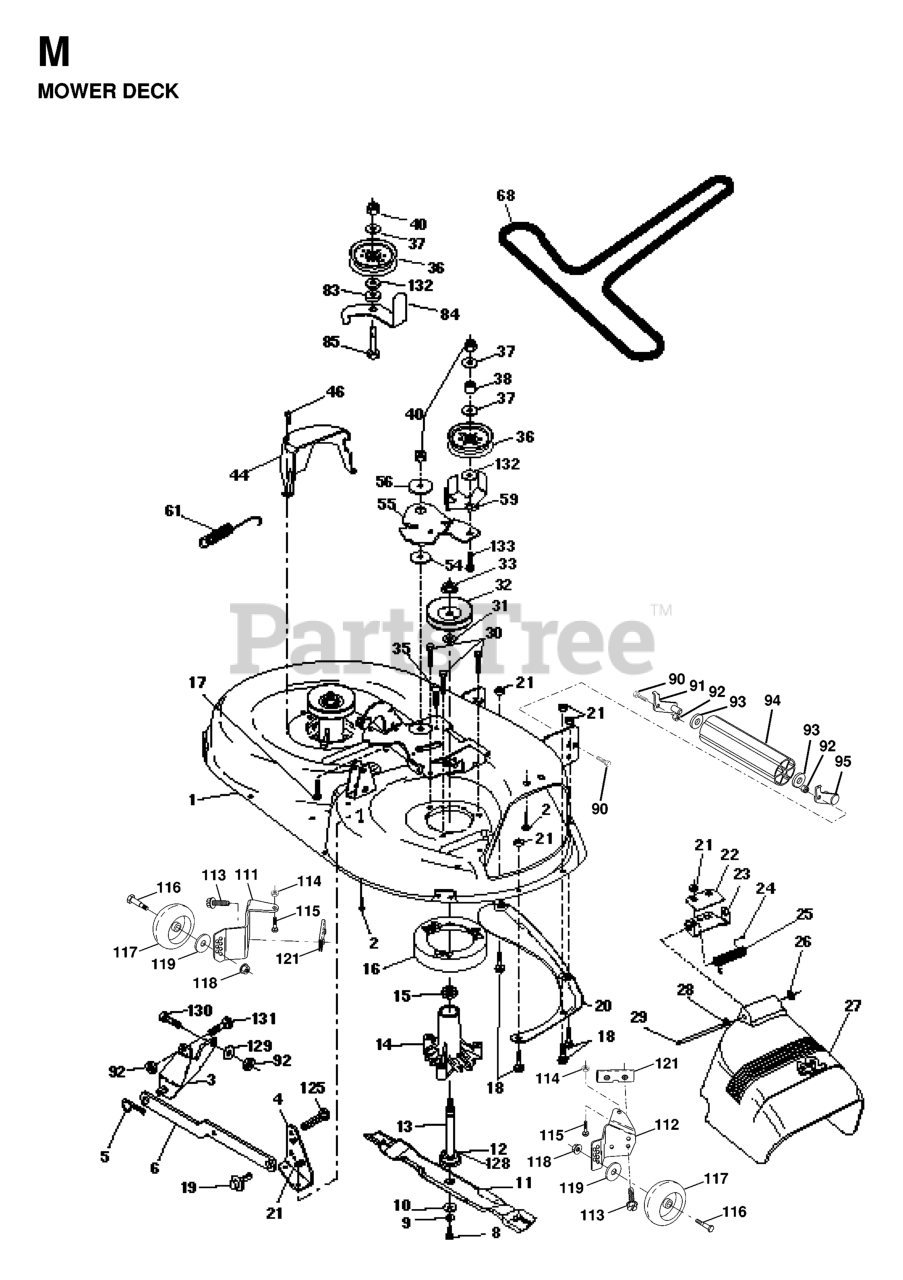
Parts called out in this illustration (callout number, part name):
1	DECK 42"
2	RP BOLT 5/16-18 X3/4 ZN/YEL GR
3	BRKT ASM SWAY BAR
4	BRKT DECK SW BAR
5	RETAINER-SPRNG RB
6	REAR SUSP ARM
8	BLADE BOLT
9	LOCKWASHER
10	WASHER.BLADE
11	BLADE 42", YTH 160
12	BEARING.BALL.#6204.(MANDREL)
13	SHAFT ASM VENT
14	HOUSING.MANDREL.VENTED (MACHD)
16	STRIPPER
17	BOLT CARRIAGE
18	BOLT
19	BOLT SHD 5/16-18
20	BAFFLE
21	LOCKNUT
22	STIFFENER BRACKET
23	DEFLECTOR BRACKET
24	CAP-SLEEVE LT
25	SPRING TORSION
26	NUT PUSH M
27	SHIELD.DEFLECTOR.MOWER.42".BLK
28	Washer 11/32 x 5/8 x 16 Ga SD
29	ROD.HINGE
30	SCREW
31	WASHER
32	PULLEY/MANDREL
33	NUT
35	FASTENER.XMAS.TREE
36	FLAT IDLER PULLEY
37	WASHER
38	IDLER SPRING SPACER
44	GUARD MANDREL LH BLACK
46	SCREW.1/4-20X5/8
54	HARDENED WASHER
55	IDLER ARM
56	SPACER RETAINER
59	GUARD, BELT
61	SPRING EXTENSION
84	KEEPER.BELT.IDLER
85	BOLT
90	BOLT
91	BRACKET LH (A)
92	NUT
93	Washer 1 17/32 X 7/8 X 16 Ga
94	NOSE ROLLER
95	BRACKET RH (B)
111	BRACKET WHEEL GAUGE LH 42" DK
112	BRACKET WHEEL GAUGE RH 42" DK
113	SCREW.THDROL.5/16-18X3/4.TTY
114	NUT
115	BOLT.CARR.5/16-18X1/2
116	BOLT, SHOULDER
117	WHEEL GAGE DONUT
118	LOCKNUT
119	WASHER.5/16.FLAT.STE.STD.
121	BRACKET.EXTRUDED.GAGE.WHEEL
125	Pin Cotter 1/4 x 1 Plated
128	WASHER FELT
129	WASHER
131	BOLT D
132	Washer 13/32 x 1-3/8 x 13 Ga.
